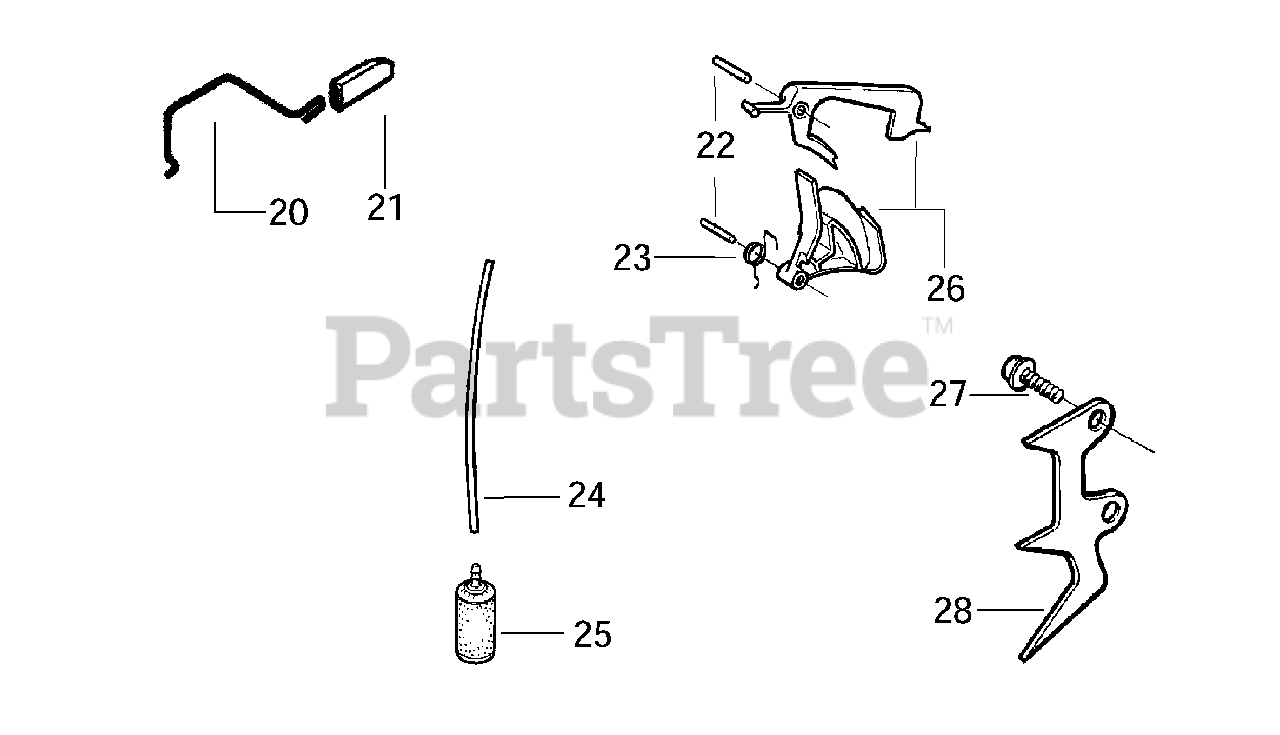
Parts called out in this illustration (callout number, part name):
20	Wire - Throttle
21	Cap - Wire
23	Spring - Starter Dog
24	Kit - Fuel line
25	Assy. Fuel Pickup
26	Kit - Throttle Trigger
28	Assy. Spike
